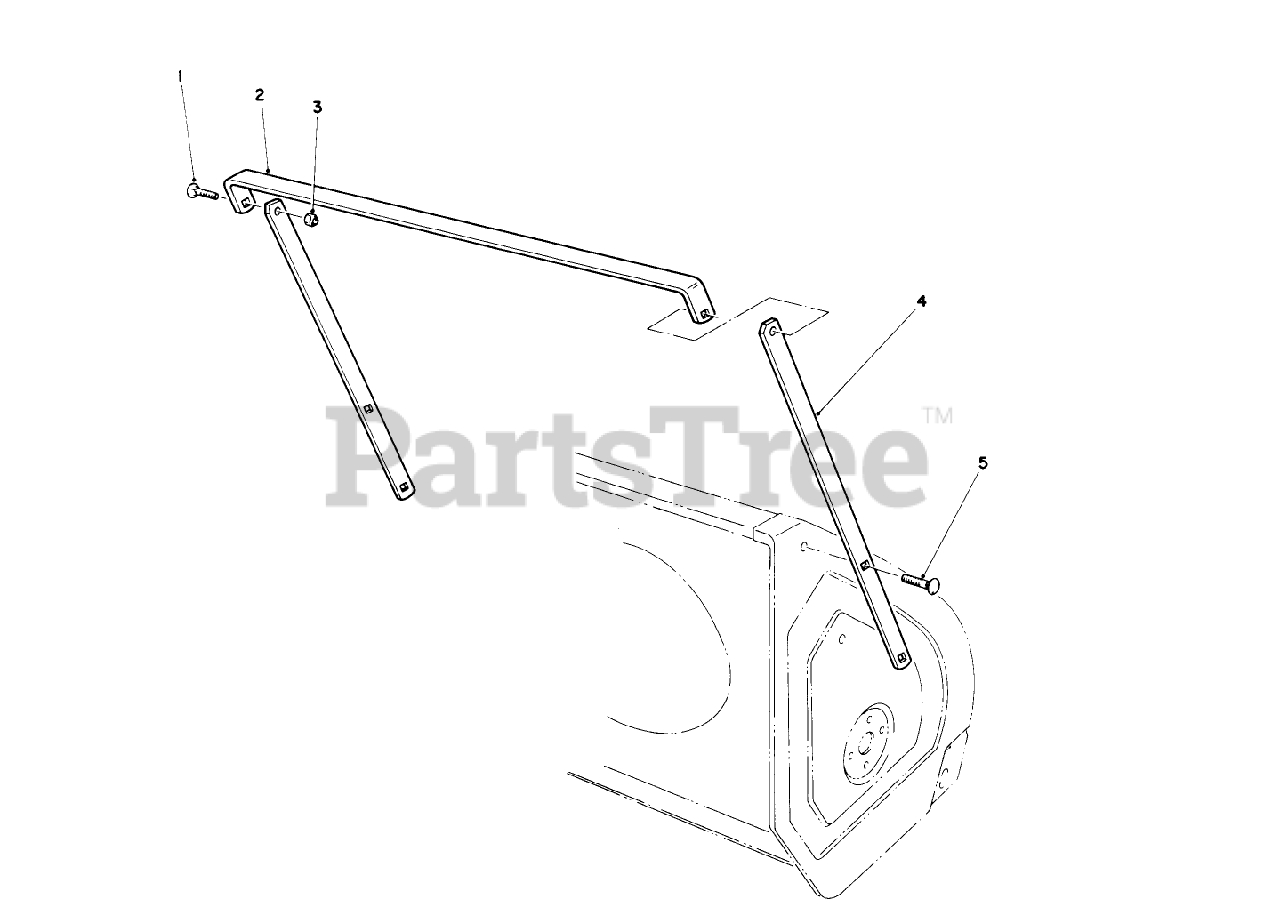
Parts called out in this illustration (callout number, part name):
1	SCREW-CARR
3	NUT-LOCK, NI
4	Breaker-Side
5	BOLT-CARR
